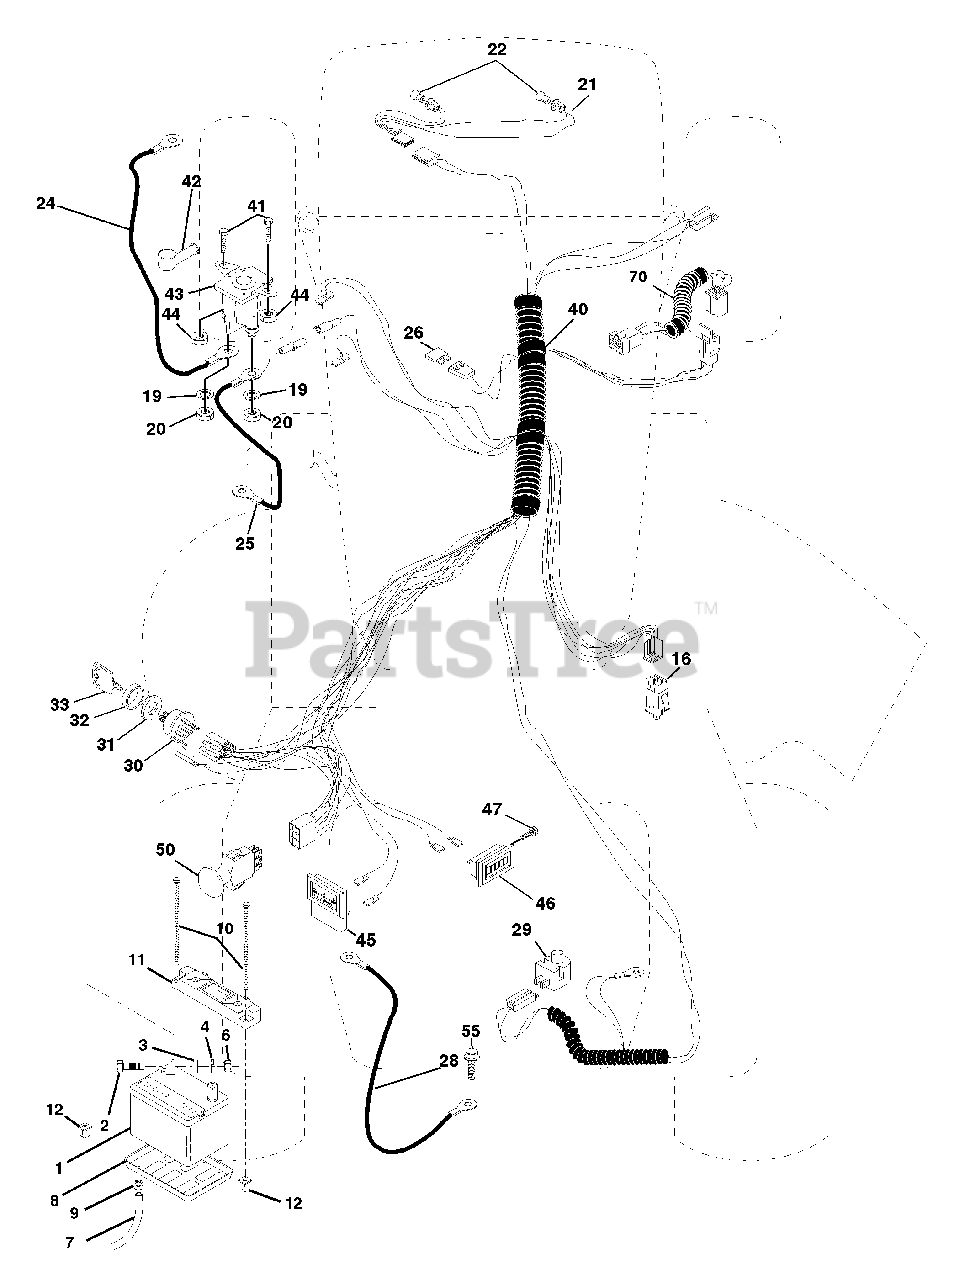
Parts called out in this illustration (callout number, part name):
1	Battery 12 Volt 35 AMP
2	Bolt Hex Hd 1/4-20unc X 3/4
3	Washer 9/32 X 5/8 X 16 Ga.
4	Washer Lock Hvy Helical 1/4
6	Nut Fin Hex 1/4-20 Unc
7	Tube Plastic 46" Front Battery
8	Case Battery Mech Hinge
9	Clamp Hose Olive
10	Bolt Brt Frt 1/4-20 x 75 Ainc
11	Holddown Battery Front Mount
12	Nut Push Nylon 1/4" Battery Frt
16	Switch Interlock Push-In
19	Washer Lock 1/4
20	Nut Jam Hex 1/4-20 Unc
21	Harness Asm Light W/4152j
22	Bulb Light #1156
24	Cable Battery 6 Ga 11" red
25	Cable Battery 6 Ga 22" red w/16 wire
26	Fuse 30 AMP Auto Green
28	Cable Ground 6 Ga 21" black
29	Switch Plunger Nc Gray
30	Switch Ign 4 pos w/lights
31	Nut Ignition
32	Cover Sw Ignition
33	Key Ign Modelled Generic
40	Harness Ign.
41	Bolt Blk Fin Hex 1/4 - 20 x 1/2
42	Cover Terminal Red
43	Solenoid
44	Nut Keps Hex 1/4-20 Unc
45	Ammeter Rectangular 15 Amp
46	Meter Hour
47	Screw 10-24 x 1/2 Black
50	Switch PTO 3 PDT Black Delta 96
51	Ring Retainer TTO
55	Screw Thdrol 5/16-18 x 1-1/2 Tyt
70	Harness, Eng.
